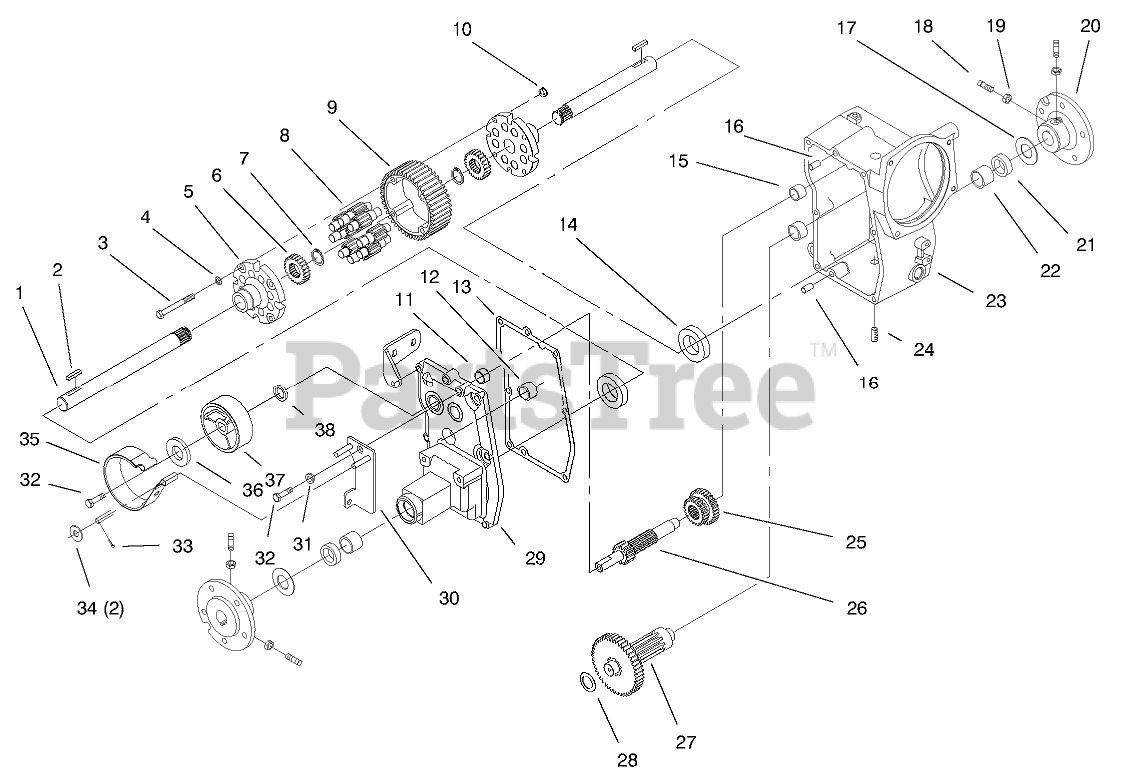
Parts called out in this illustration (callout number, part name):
1	AXLE-REAR
3	BOLT-HEX
4	WASHER
5	END CAP-DIFFERENTIAL
6	GEAR-AXLE DIFFERENTIAL
7	RING-SNAP
8	GEAR-PINION, 11T
9	GEAR-DIFFERENTIAL RING, 43T
11	BEARING-NEEDLE
12	BEARING-NEEDLE
13	GASKET-CASE
14	BEARING-BALL
15	BEARING-NEEDLE
16	PIN-LOCATING
17	WASHER-THRUST
18	SCREW-SET, SQH
19	NUT-JAM
20	HUB-WHEEL
21	SEAL-OIL
22	BEARING
23	CASE-LH
24	PLUG-PIPE
25	GEAR-SLIDING
26	SHAFT-BRAKE
27	GEAR ASM
28	WASHER-THRUST
29	CASE-RH
30	Arm-PIVOT, Brake
31	CAM-SPACER
32	SCREW-HH, LOCK
33	PIN-COTTER
34	WASHER-FLAT
35	BAND-BRAKE
36	WASHER
37	DRUM-BRAKE
38	SEAL-OIL
